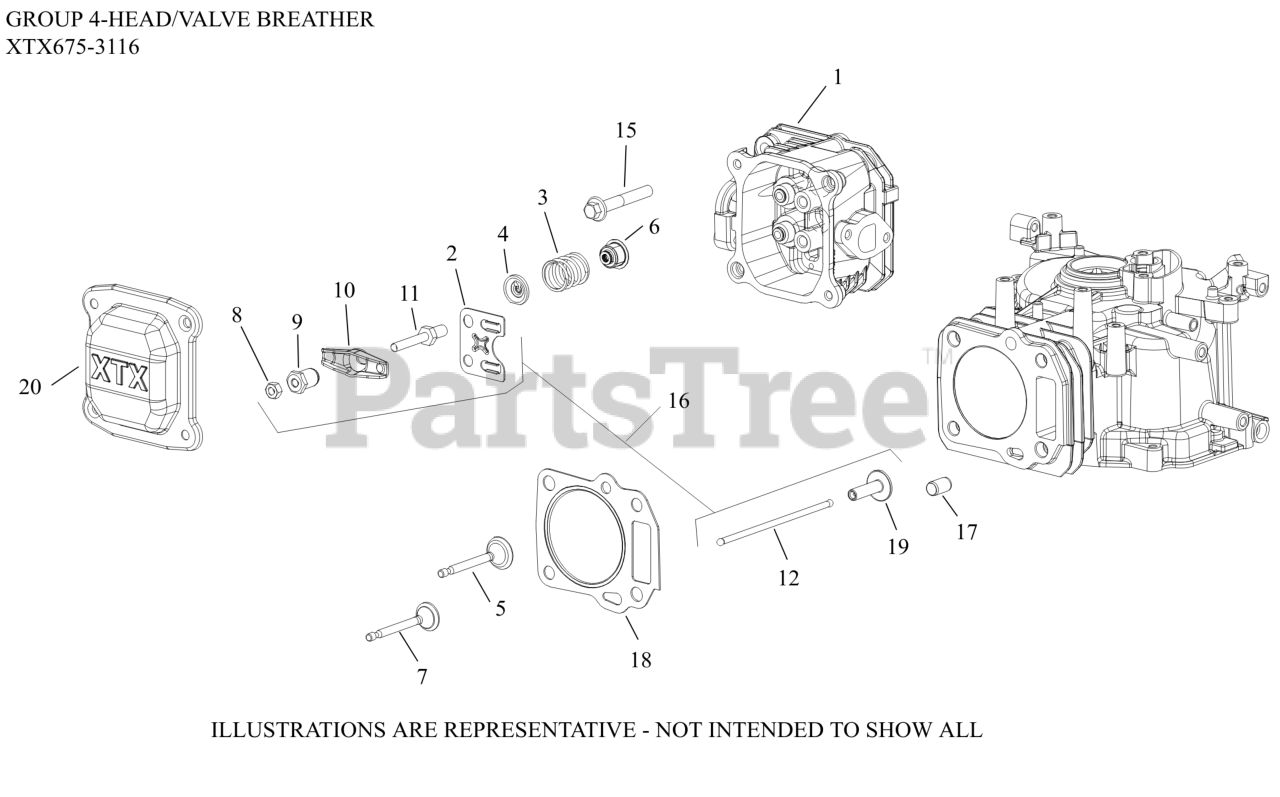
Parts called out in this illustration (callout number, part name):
1	HEAD, CYLINDER
2	PLATE, PUSHROD GUIDE
3	SPRING, VALVE
4	RETAINER, VALVE SPRING
5	VALVE INTAKE
6	SEAL, VALVE STEM
7	VALVE, EXHAUST
8	NUT, HEX JAM
9	PIVOT, ROCKER ARM
10	ARM, ROCKER
11	STUD, ROCKER ARM-USE 14 072 22-S
12	ROD, PUSH
15	SCREW, HEX FLANGE M8
16	KIT, VALVE TRAIN
17	DOWEL, CYLINDER HEAD
18	KIT HEAD GASKET
19	LIFTER, VALVE
20	COVER, VALVE
